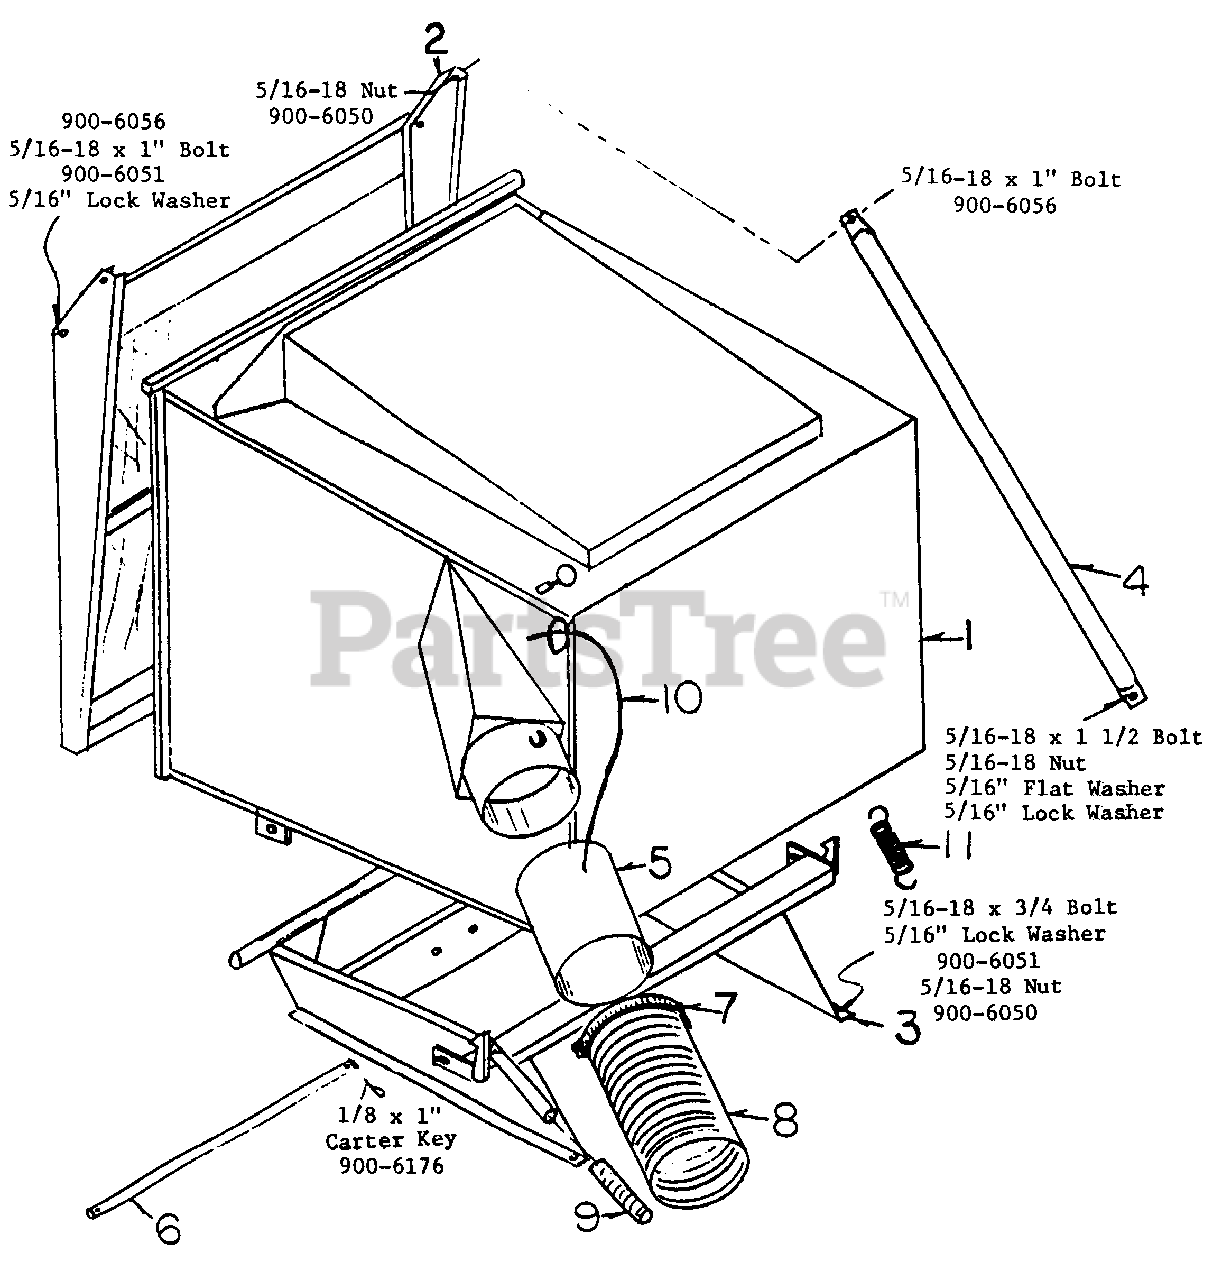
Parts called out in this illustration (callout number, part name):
1	CROSS BOX
3	BOX MOUNT
4	DOOR LINKAGE
5	MALE TUBE
8	HOSE
9	HANDLE GRIP
10	MALE TUBE ROPE
